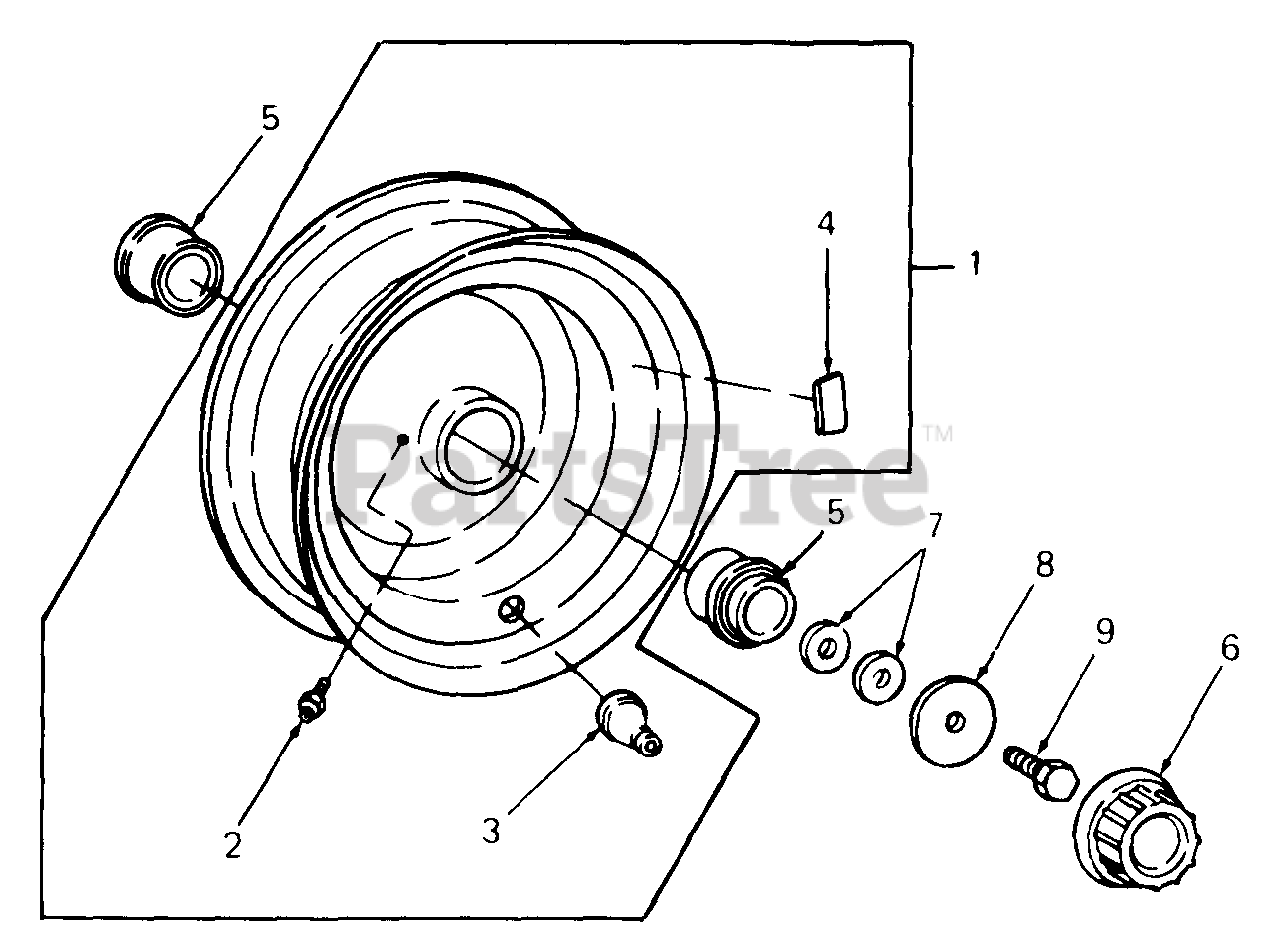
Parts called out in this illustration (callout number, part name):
1	Wheel Assy, Front
2	Fitting, Lube
3	Valve, Tubeless Air
4	Label, Inflation
5	Bearing, Wheel Ball
6	Cap, Hub
7	Washer, Flat, .531 X 1.25 X .100 Thk
8	Washer, Flat, .535 X 1.92 X .060 Thk
9	Bolt, Patch, 1/2-13 X 1.0 Lg GR5
